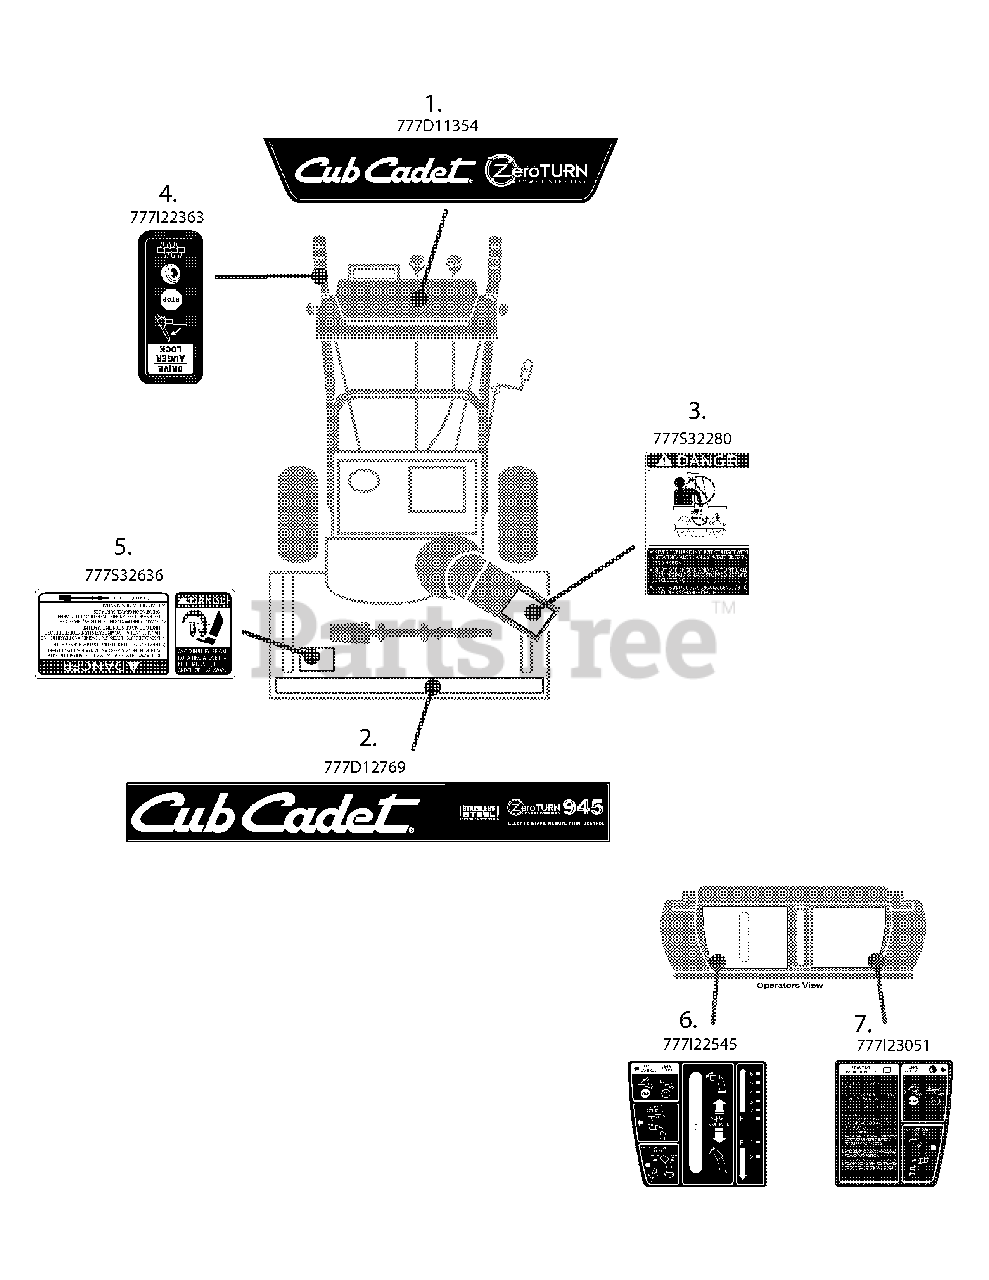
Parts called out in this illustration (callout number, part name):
1	Cub Handle Panel Label
2	Cub Auger Housing Label
3	Snow Chute Danger Label
4	Drive/Auger Handle Label
5	Auger Housing Danger Label
6	Handle Panel Label LH
7	Handle Panel Label RH
